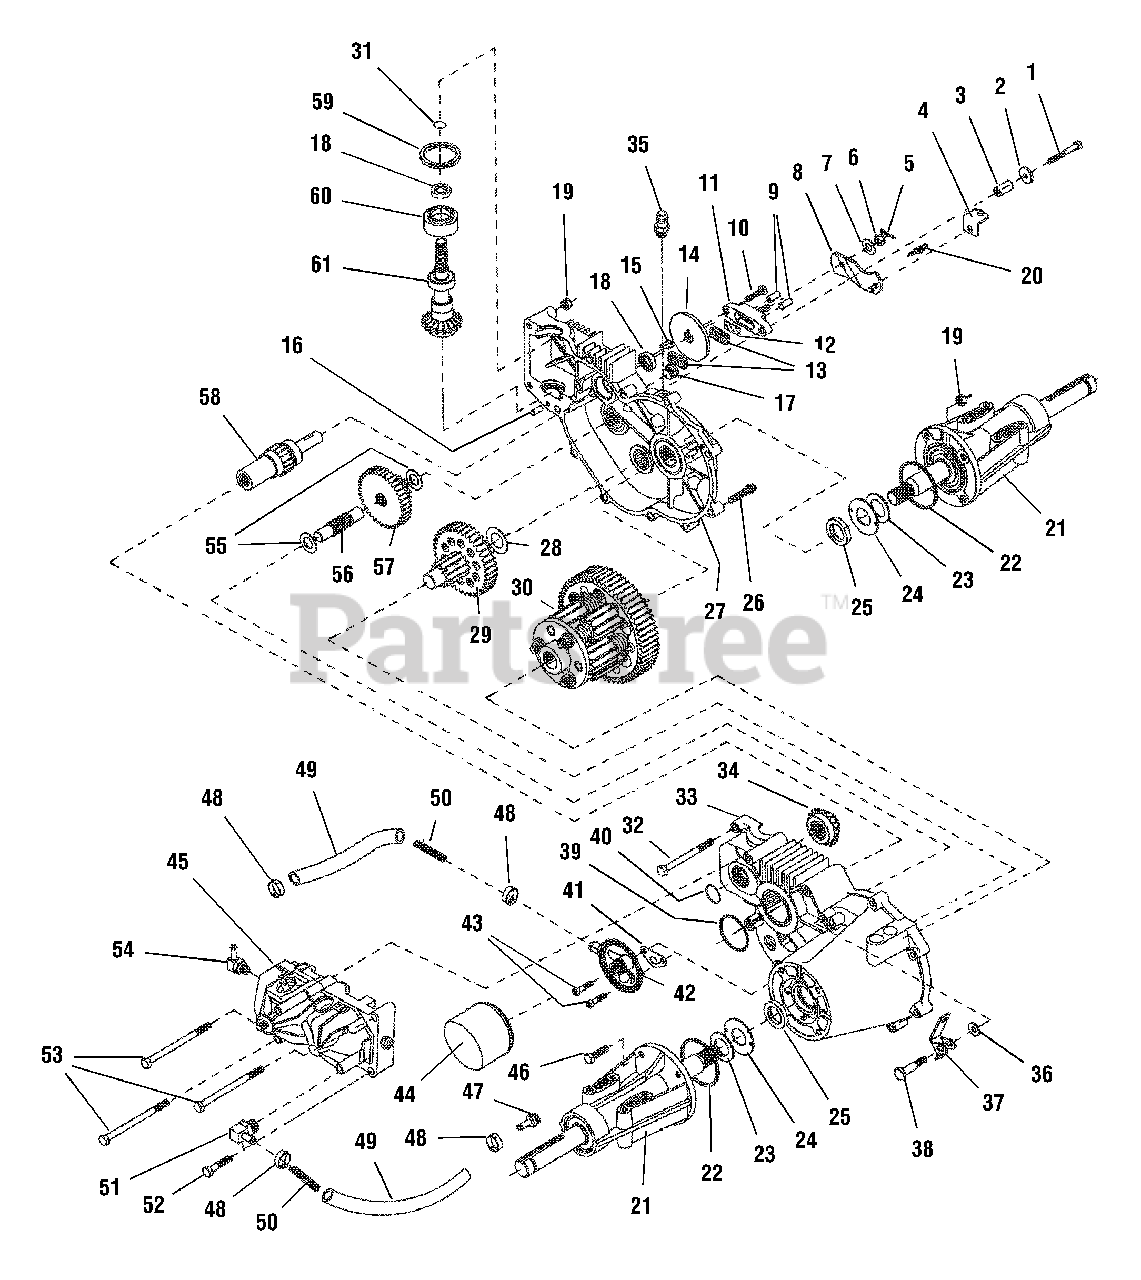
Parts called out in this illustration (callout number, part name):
1	BOLT, 1/4-20 x 2
2	WASHER, Flat
5	COTTER PIN
6	NUT, Castle, 7/16
7	WASHER, 7/8 x 7/16
9	PIN, Brake Actuating
10	BOLT, Nyloc, Gr. 5, 1/4-20 x 1
11	BRAKE YOKE ASSY.
12	PLATE, Puck
13	PUCK, Brake
14	DISC, Brake
15	KEY, Hi-Pro, 3/16 x 5/8
17	PLUG, Straight Thread
18	SEAL, Oil, 5/8 x 1 x 1/4
19	NUT, Hex, 5/16-18
20	SPRING, Extension
21	AXLE MOUNTING HORN ASSY.
22	O-RING
23	WASHER, 1 x 1-5/8 x 5/64
24	WASHER, 1 x 2-1/16 x 3/32
25	OIL SEAL, 63/64 x 1-1/2 x 1/4
26	CAPSCREW, Torx Hd., 5/16-18
27	HOUSING ASSY., RH
28	WASHER, 7/8 I.D. X 1-1/2 O.D.
29	FINAL DRIVE PINION ASSY.
30	DIFFERENTIAL ASSY.
31	RING, Wire Retaining
32	BOLT, Hex Hd., 5/16-18 x 3-1/2
33	HOUSING ASSY., LH
34	PINION ASSY.
35	FITTING/O-RING ASSY.
37	ARM, Freewheel Actuating
38	BOLT, Shoulder
39	O-RING
40	QUAD RING
41	GASKET, Filter Base
42	BASE, Filter Assy.
43	CAPSCREW, 1/4-20 x 1
44	FILTER, Spin-on, Bypass
45	HYDRO PUMP
46	CAPSCREW, Hex, Gr. 5, 5/16-18 x 1
47	FITTING, 1/2, Straight, 9/16, SAE
48	PINCH CLAMP
49	HOSE, 1/2", 8-3/4" Long
51	FITTING, 1/2, Beaded, 90°, 7/8, SAE
52	BOLT, Hex, Gr. 5, 5/16-18 x 1-3/4
53	BOLT, Hex, Gr. 5, 5/16-18 x 1/2
54	FITTING, 1/2, Beaded, 90°, 9/16, SAE
55	WASHER, 5/8 I.D. X 1-5/32 O.D.
57	GEAR, Reduction, 14T-38T
58	BRAKE SHAFT ASSY.
59	QUAD RING
60	BEARING, Retainer
61	INPUT ASSY.
